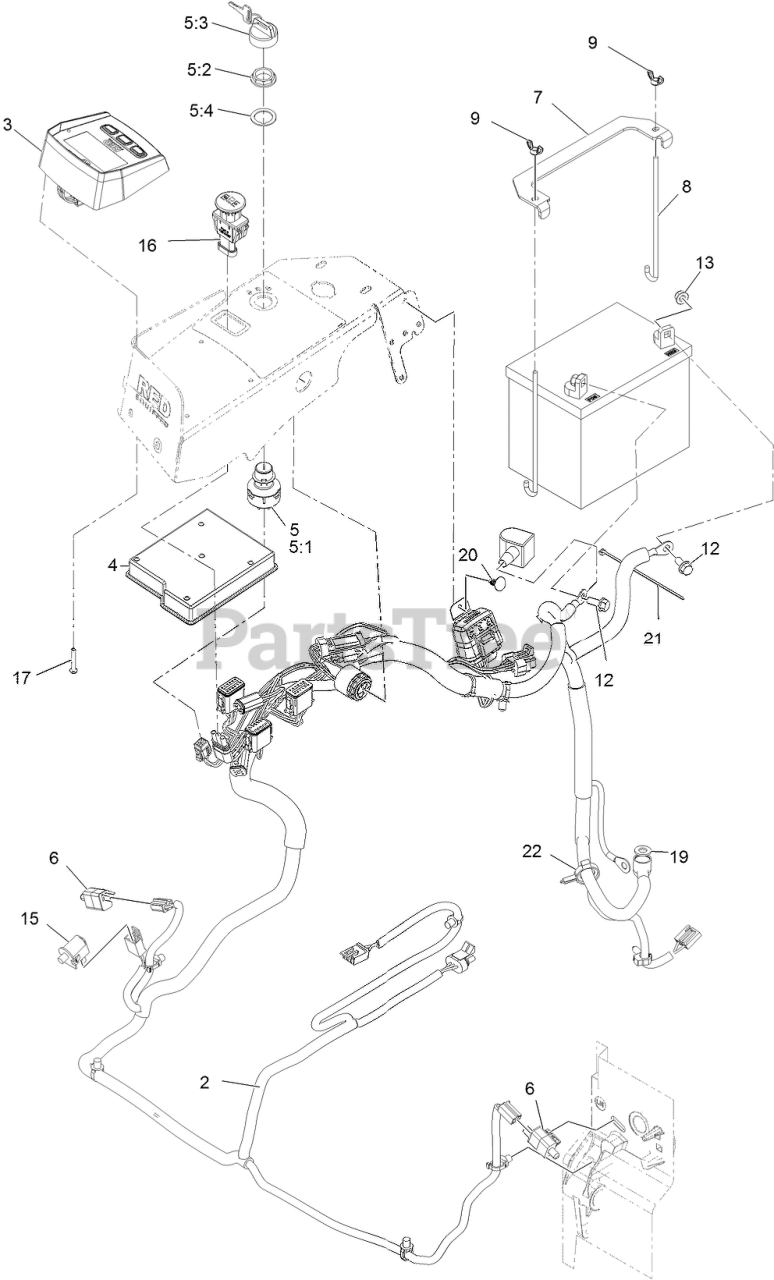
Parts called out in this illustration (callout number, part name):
2	Harness-Wire
3	MODULE, LDU
4	Module-Mcu
5	IGNITION SWITCH ASM
5:1	Switch-Ignition
5:2	NUT-MOUNTING
5:3	IGNITION KEY SET
5:4	WASHER-BACKUP
7	STRAP-TIE DOWN, BATTERY
8	BOLT-HOLDDOWN
9	WINGNUT
12	SCREW-HHF
13	NUT-HF, NI
15	SWITCH-BAIL
16	SWITCH-PTO, SEALED
17	SCREW-PPH
19	WASHER-FLAT
20	PLUG-PLASTIC
21	TIE-CABLE
22	CLAMP-HOSE
